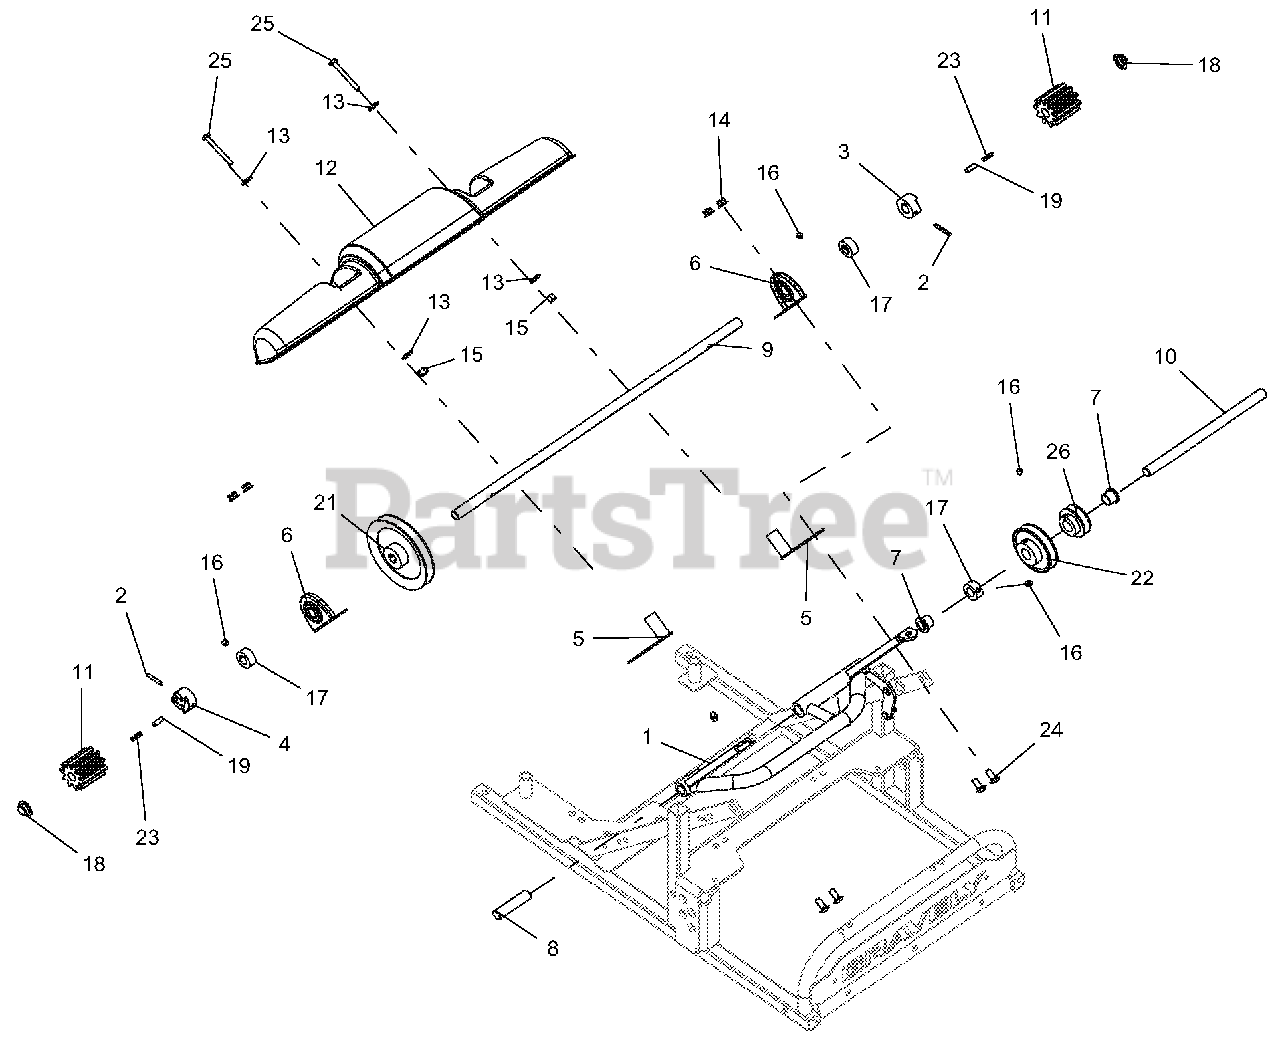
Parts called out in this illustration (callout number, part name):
1	WMT-SELF PROPEL FRAME (BLACK)
2	PIN-ROLL .188X1.25
3	CLUTCH, RIGHT SP
4	CLUTCH, LEFT SP
5	WLDMT, SP BELT COVER MOUNTING (BLACK)
6	BEARING ASSY, SP TOPSHAFT, HWM
7	BUSHING, FLANGED .75X.625X.62
8	SHAFT, PIVOT SHORT
9	SHAFT, WHEEL DRIVE
10	SHAFT, PIVOT LONG
11	GEAR, DRIVE (SP)
12	COVER, PLASTIC -SP (HIGH WHEEL)
13	WSHR-FL-STL.312X.734X.065 YWZ
14	NUT-LK-NYL-FLG .31-18 YWZC
15	NUT-LK-NYL .250-20 YWZC
16	SET SCREW 5/16-18 X 5/16 CP
17	SET COLLAR .625ID X .50
18	NUT, PUSH .625 DIA. PAL
19	DOWEL PIN 1/4 X 3/4
21	PULLEY, 5" OD X 5/8" ID
22	WMT,DBL SP IVP PULLEY 17344K
23	SPRG, COMPRESSION
24	BLT-RHDSSQNK .31-18X.75 G5YZ
25	BLT-HEX .25-20X2.25 GR5 YWZC
26	PULLEY, 2"O.D.X3/4"I.D.NO KEY
